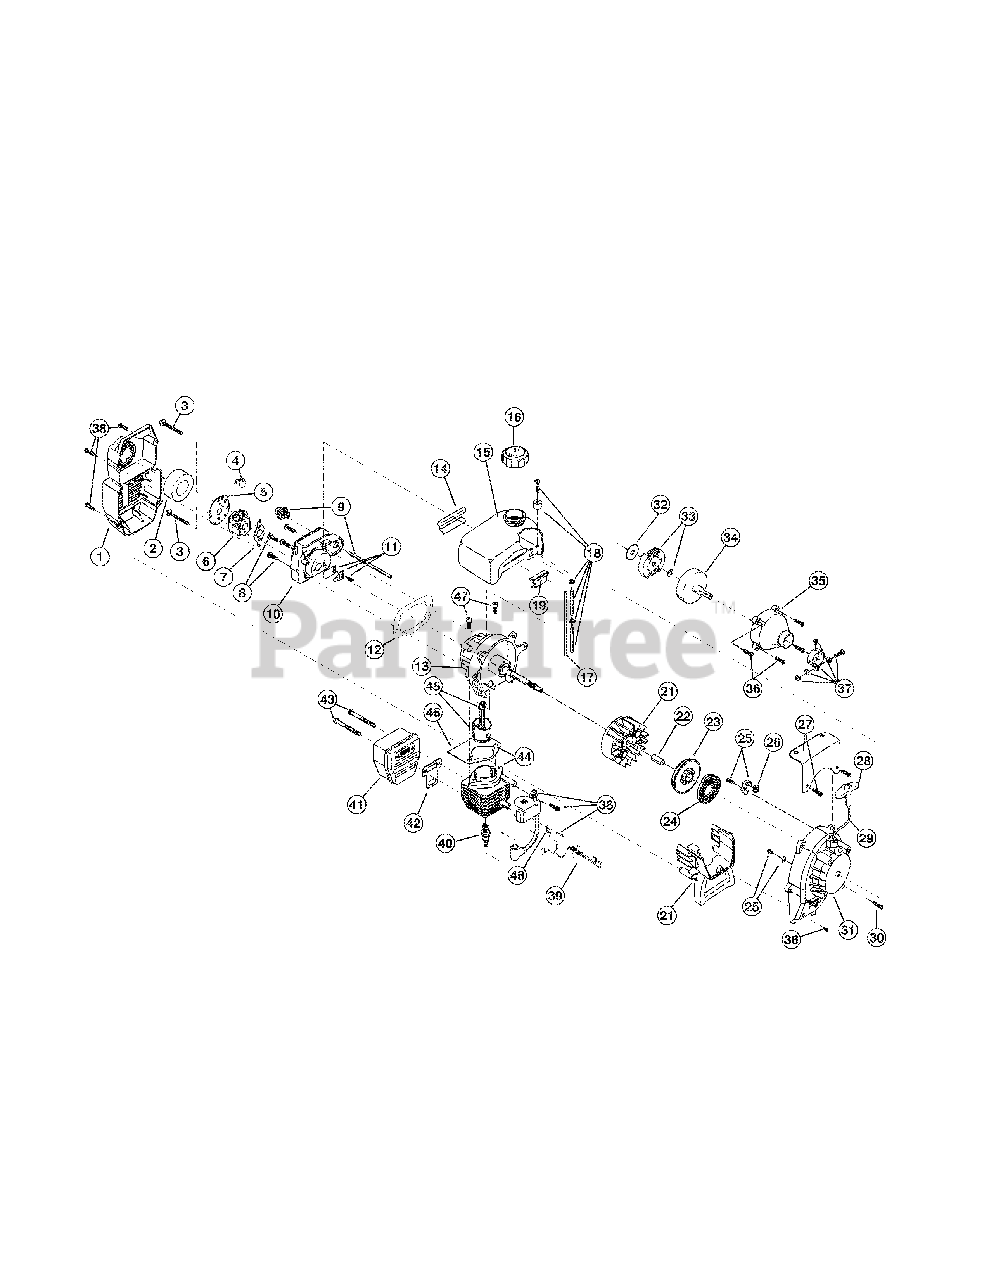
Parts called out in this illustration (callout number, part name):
1	Air Cleaner Assembly (includes 2 & 36)
2	Air Cleaner Filter
3	Carburetor Mounting Screw Assembly
4	Choke Lever
5	Choke Plate
6	Carburetor Assembly (includes 7 & 18)
7	Carburetor Gasket
8	Carb Mount Screw
9	Primer and Hose Assembly
10	Carb Mount Assembly (includes 8, 11 & 12)
11	Reed Assembly
12	Carburetor Mount Gasket
13	Crank Case Service Assembly (includes 8)
14	Rear Mounting Pad
15	Fuel Tank Assembly (includes 16-18)
16	Fuel Cap Assembly
17	Fuel Return Line
18	Fuel Line Assembly
19	Front Mounting Pad
20	Shroud Extension and Stand (includes 36
21	Flywheel Assembly
23	Recoil Pulley
24	Recoil Spring
25	Pulley Retainer Assembly
26	Rope Guide
27	Fuel Tank Guard Assembly
28	Pull Handle
30	Housing Screw
31	Starter Housing Assembly (includes items 23-26, 28-30 & 36)
32	Clutch Washer
33	Clutch Rotor Assembly
34	Clutch Drum Assembly
35	Clutch Cover Assembly (includes 36)
36	Clutch Cover Screw
37	Upper Clamp Assembly
38	Module Assembly
39	Wire Lead
40	Spark Plug
41	Muffler Assembly (includes item 42 & 43)
42	Exhaust Gasket
43	Muffler Mounting Bolt Assembly
44	Cylinder Assembly (includes items 46 & 47)
45	Piston & Rod Assembly
46	Cylinder Gasket
47	Cylinder Bolt
48	Ground Tab
